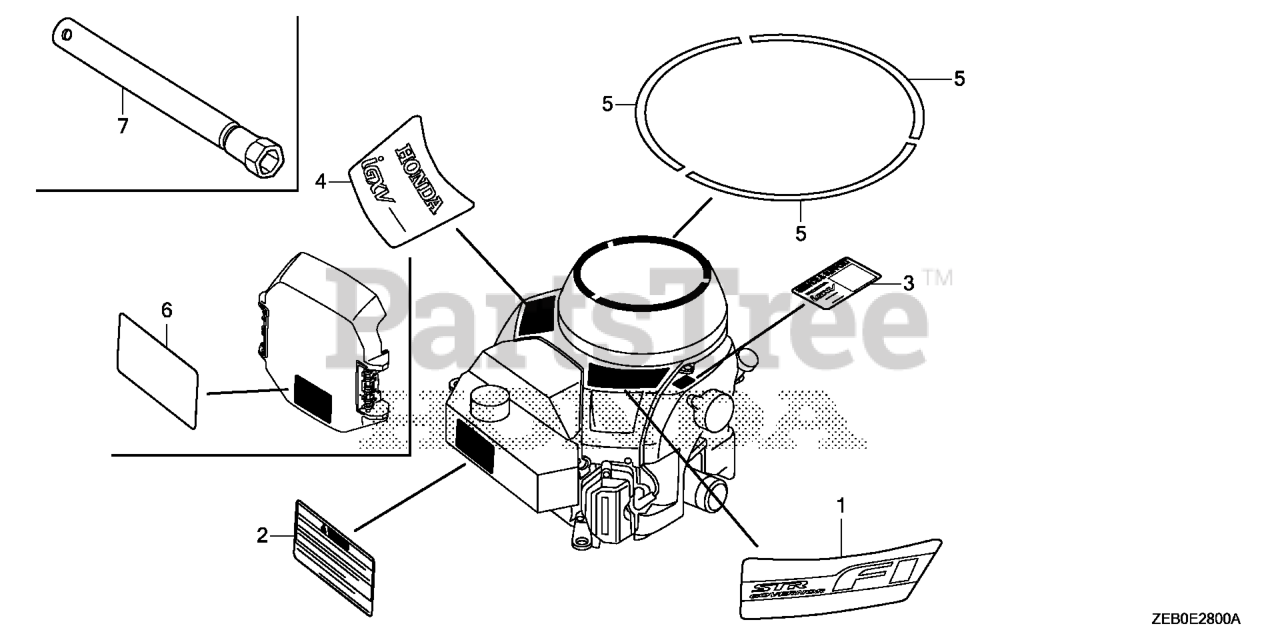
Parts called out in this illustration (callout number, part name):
3	LABEL, QR CODE (SERVICE)
4	EMBLEM (GXV800)
6	MARK, OPERATOR CAUTION (PICTOGRAPH)
7	WRENCH, SPARK PLUG
